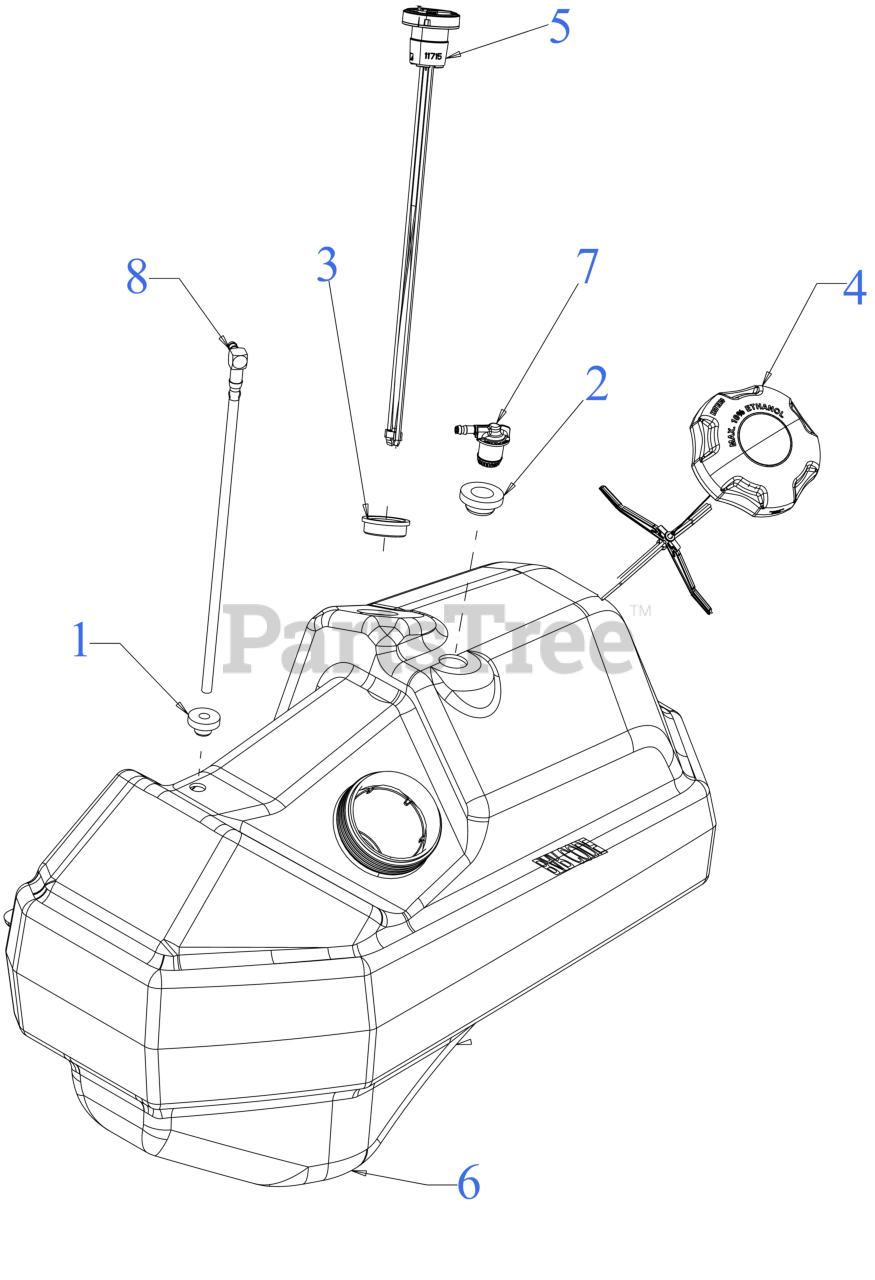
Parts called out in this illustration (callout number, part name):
1	GROMMET-FUEL TANK
2	GROMMET .755 x .955 x .55
3	GROMMET 1.174X1.400X0.505
4	FUEL CAP - 3.50" ONE WAY VENT
5	FUEL GAUGE
6	FUEL TANK (7.25 GAL) (RH)
7	FUEL VENT FITTING
8	FUEL PICKUP VALVE (NO/SHUTOFF)
